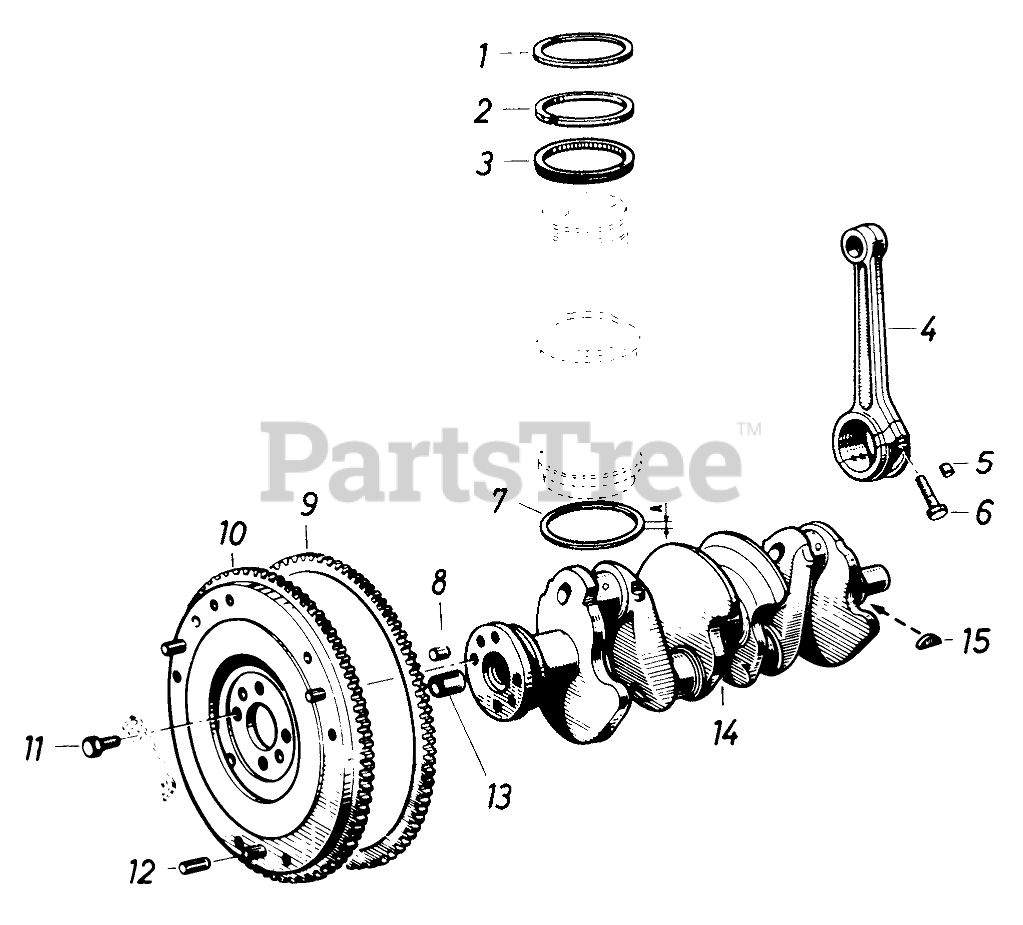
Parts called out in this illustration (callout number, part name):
1	Compression Ring
2	Oil Scraper Ring
3	Oil Piston Ring
4	Connection Rod G/351-359
5	Dowel Pin
6	Connecting Rod Bolt
7	Gasket Ring
8	Dowel Bolt
9	Ring Gear
10	Flywheel
11	Screw
12	Dowel Pin
13	Bushing
14	Crankshaft
